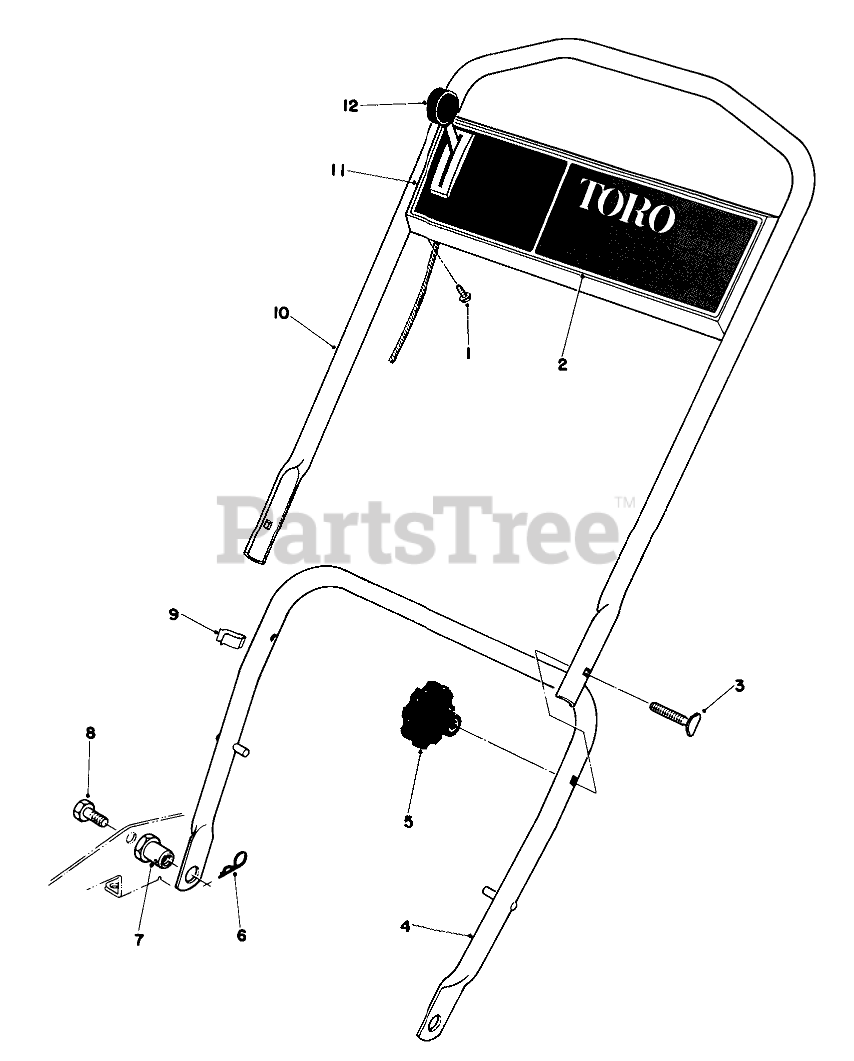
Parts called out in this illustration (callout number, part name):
1	SCREW-HWHTF
2	Decal Control Plate
3	SCREW-HANDLE
4	LOWER HANDLE ASM
6	PIN-COTTER, HAIR
7	HANDLE PIVOT NUT
8	SCREW-HH
10	UPPER HANDLE
11	Control Plate
12	Throttle Control
